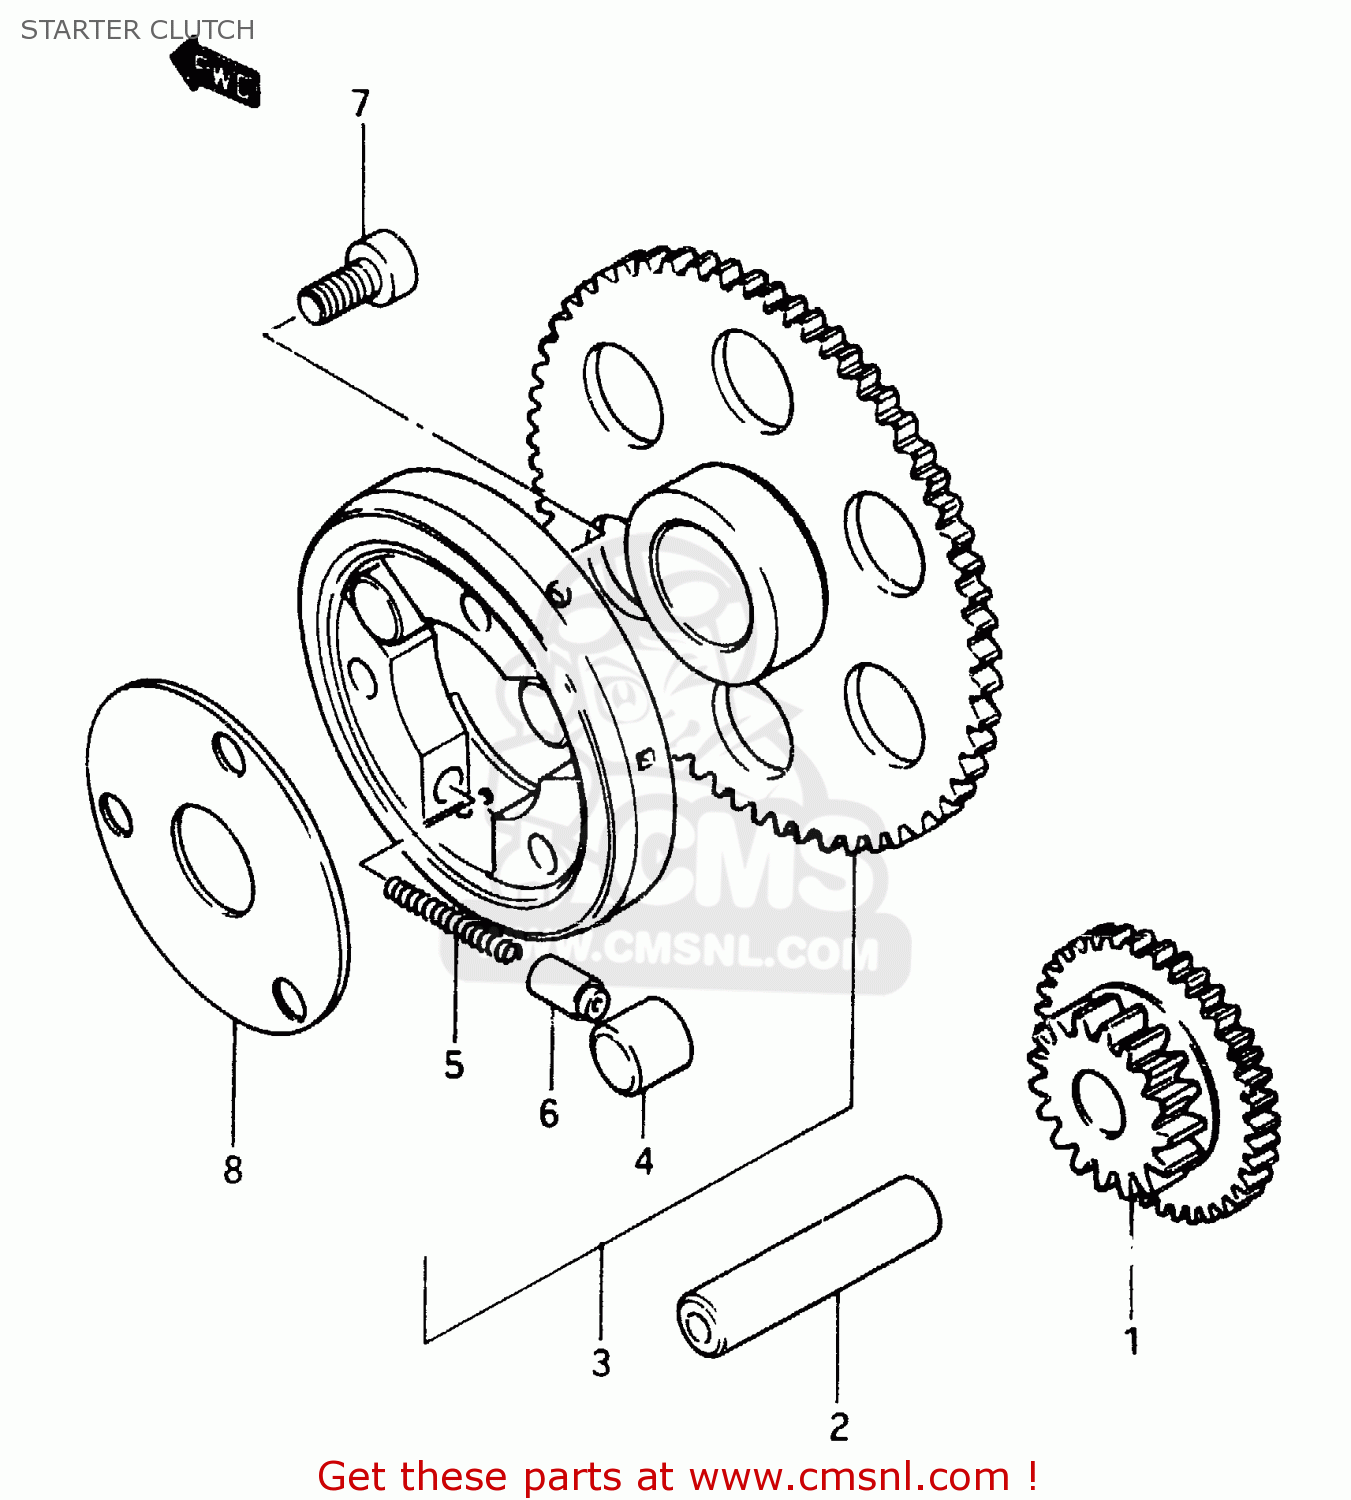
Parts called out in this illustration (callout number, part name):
1	GEAR, STARTER IDLE (NT:47/18)
2	PIN(7.4X13X40)
3	STARTER CLUTCH SET
4	ROLLER(15X13)
5	SPRING
6	PIECE,PUSH
7	BOLT
8	SHIM,STARTER CLUTCH HUB
